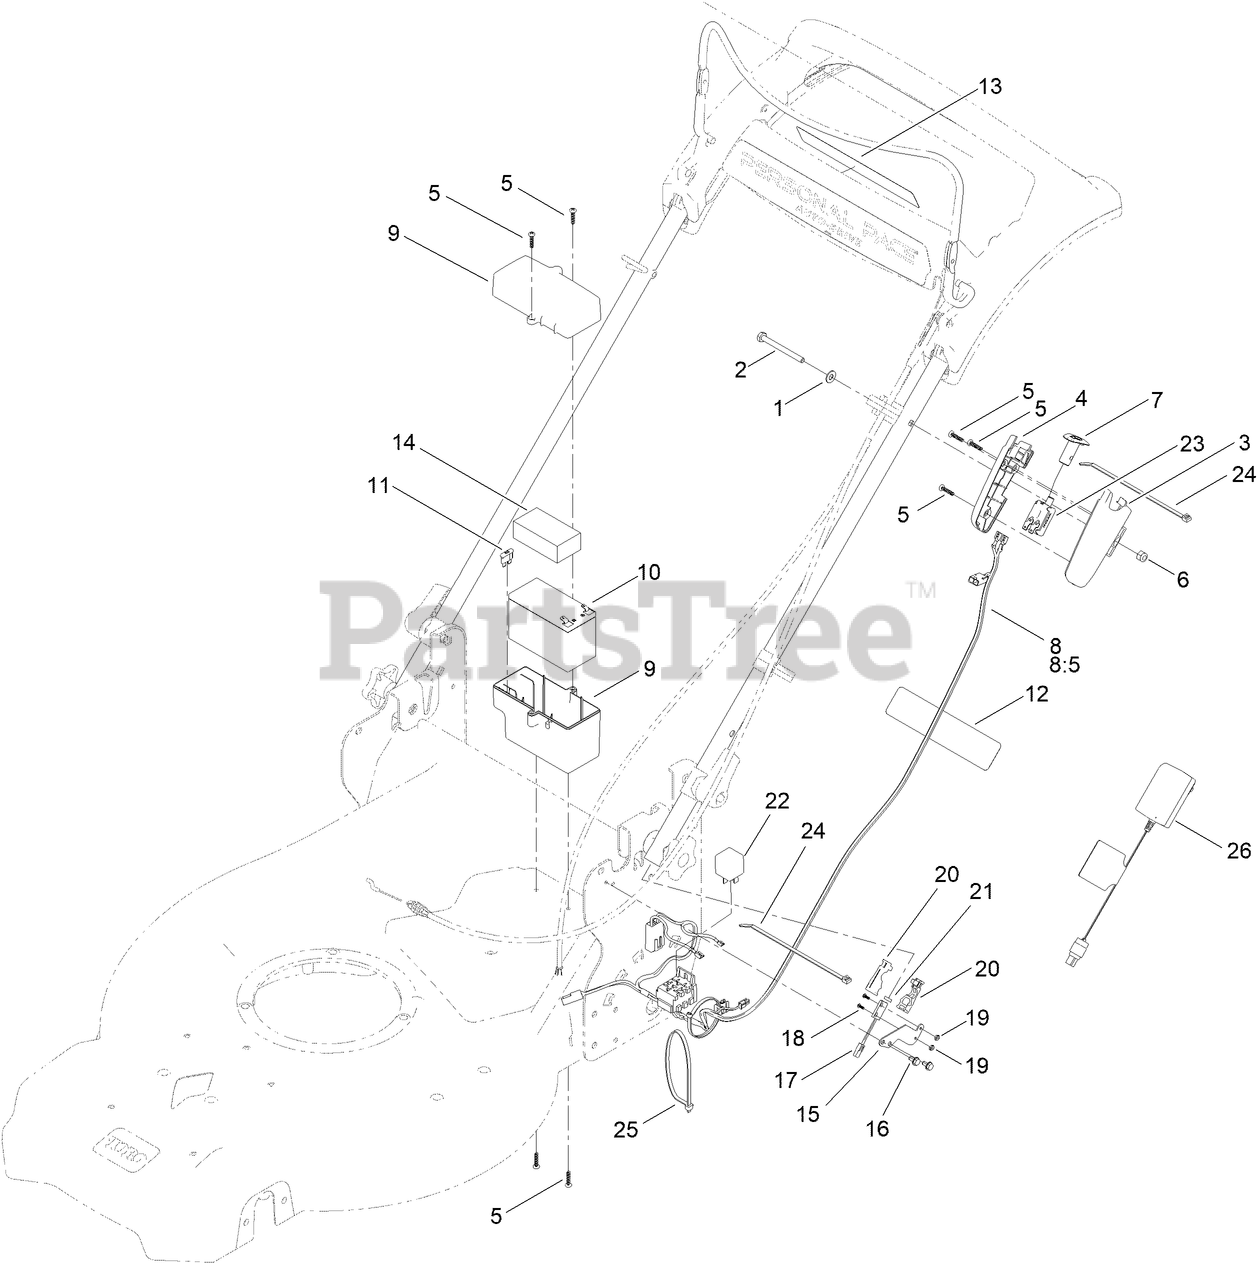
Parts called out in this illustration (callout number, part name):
1	WASHER-FLAT
2	SCREW-HH
3	HOUSING-SWITCH, LH
4	HOUSING-SWITCH, RH
5	SCREW-PPH
6	NUT-HEX
7	BUTTON-SWITCH
8	HARNESS-WIRE, SR5 VERT STOW
8:5	FUSE-40 AMP
9	BATTERY BOX ASM
10	BATTERY-NONSPILLABLE, 12 V
11	FUSE-40 AMP
12	DECAL-BATTERY CHARGING
13	DECAL-BUTTON, PUSH
14	FOAM-BATTERY, TOP
15	BRKT-SWITCH, SS
16	SCREW-HWH
17	REED SWITCH ASM
19	NUT-LOCK, NI
20	HOUSING-MAGNET
21	MAGNET
23	SWITCH-PUSH BUTTON
24	TIE-CABLE
25	TIE-CABLE
26	CHARGER, BATTERY (12V)
